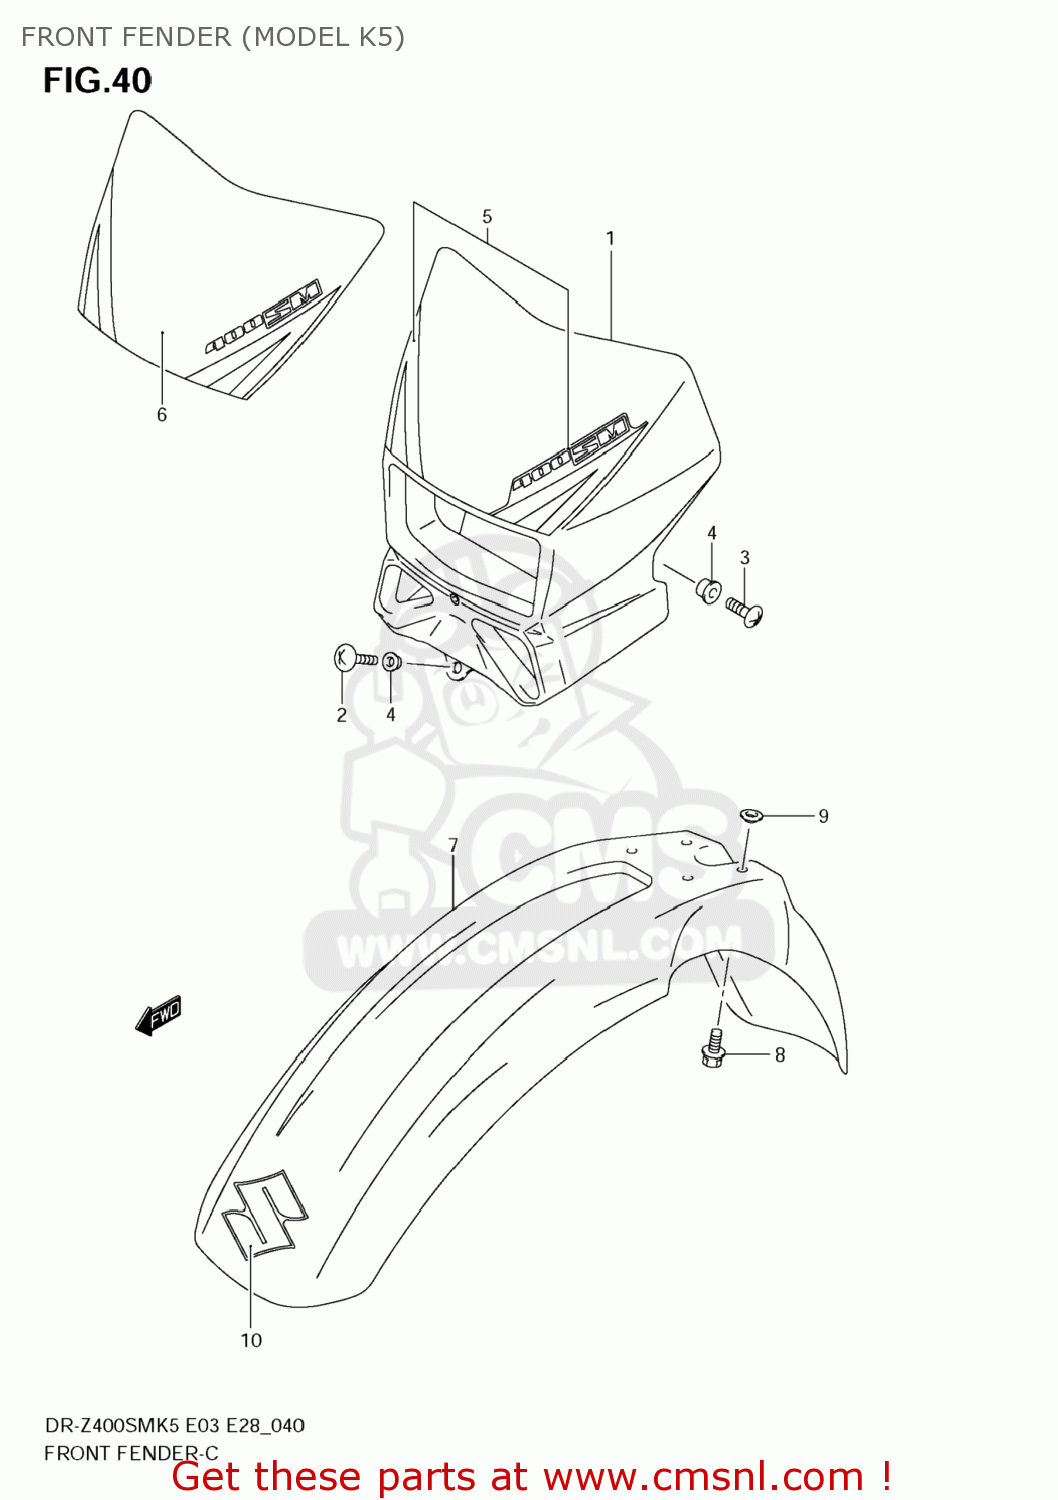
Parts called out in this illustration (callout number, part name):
1	COVER,HEADLAMP
2	SCREW
3	SCREW
4	WASHER
5	TAPE SET,HOUSING
6	TAPE,HOUSING
7	FENDER,FR
8	BOLT(6X16)
9	WASHER
10	EMBLEM,S
